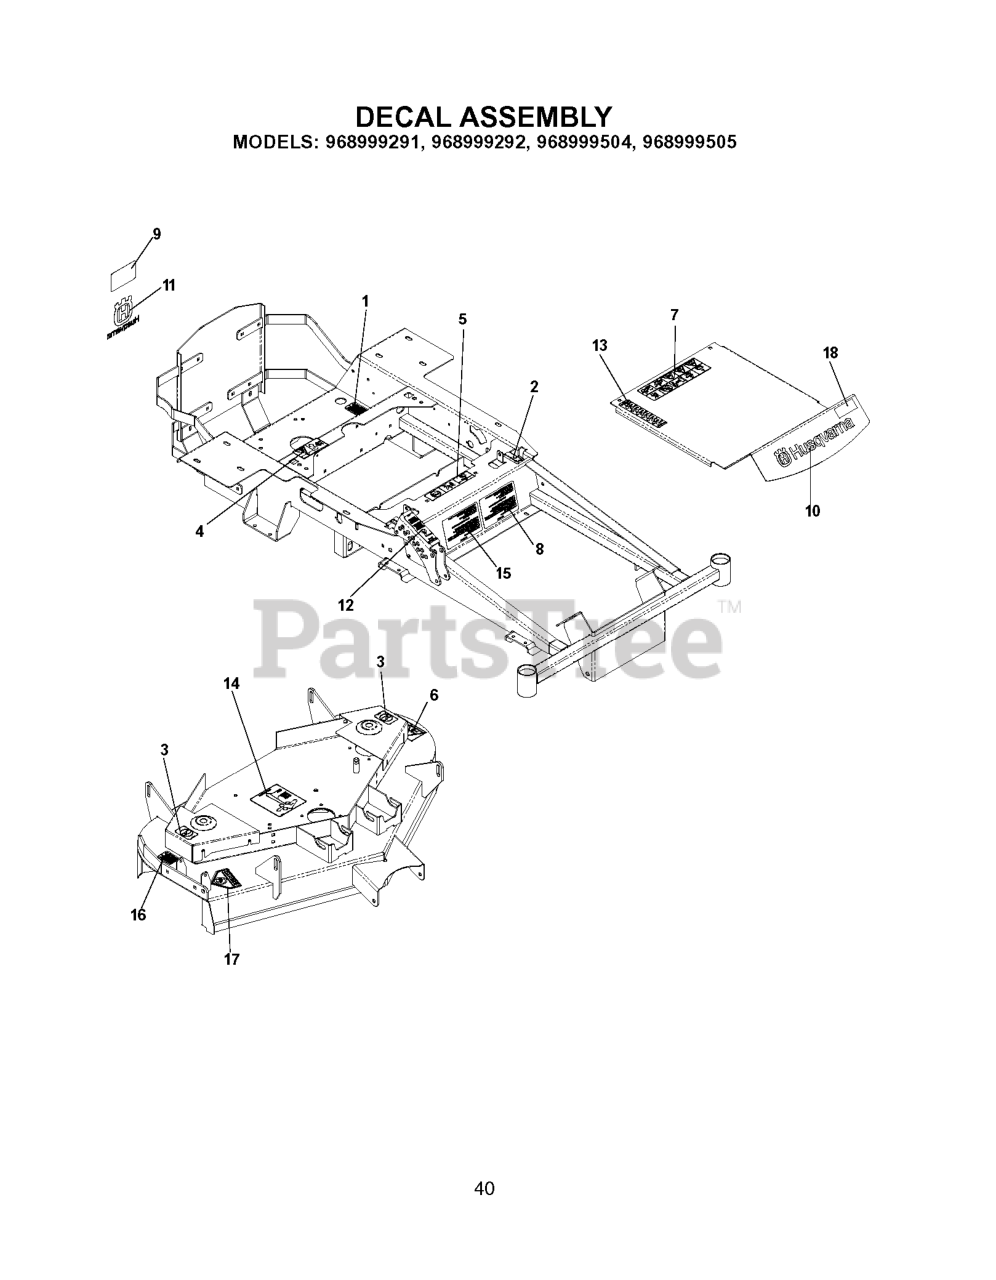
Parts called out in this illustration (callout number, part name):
1	DECAL, PROP. 65
2	DECAL, MOTION CONTROL
3	DECAL, NO STEP
4	DECAL, BELT DRIVE
5	EURO DECAL-BATTERY WARNIN6
6	DECAL, EURO SEVERING
7	DECAL, WARNING
8	DECAL, START
9	DECAL, DO NOT TOW
10	DECAL, HUSQ 12" BLUE
11	DECAL, CROWN H 5-1/4 SILVER
12	DECAL, TRANS RELEASE
13	DECAL, HEIGHT ADJUST
14	DECAL, BELT ROUTING
15	DECAL, WARNING
16	DECAL, CAUTION
17	DECAL, CPSC
18	DECAL, EZ4819
